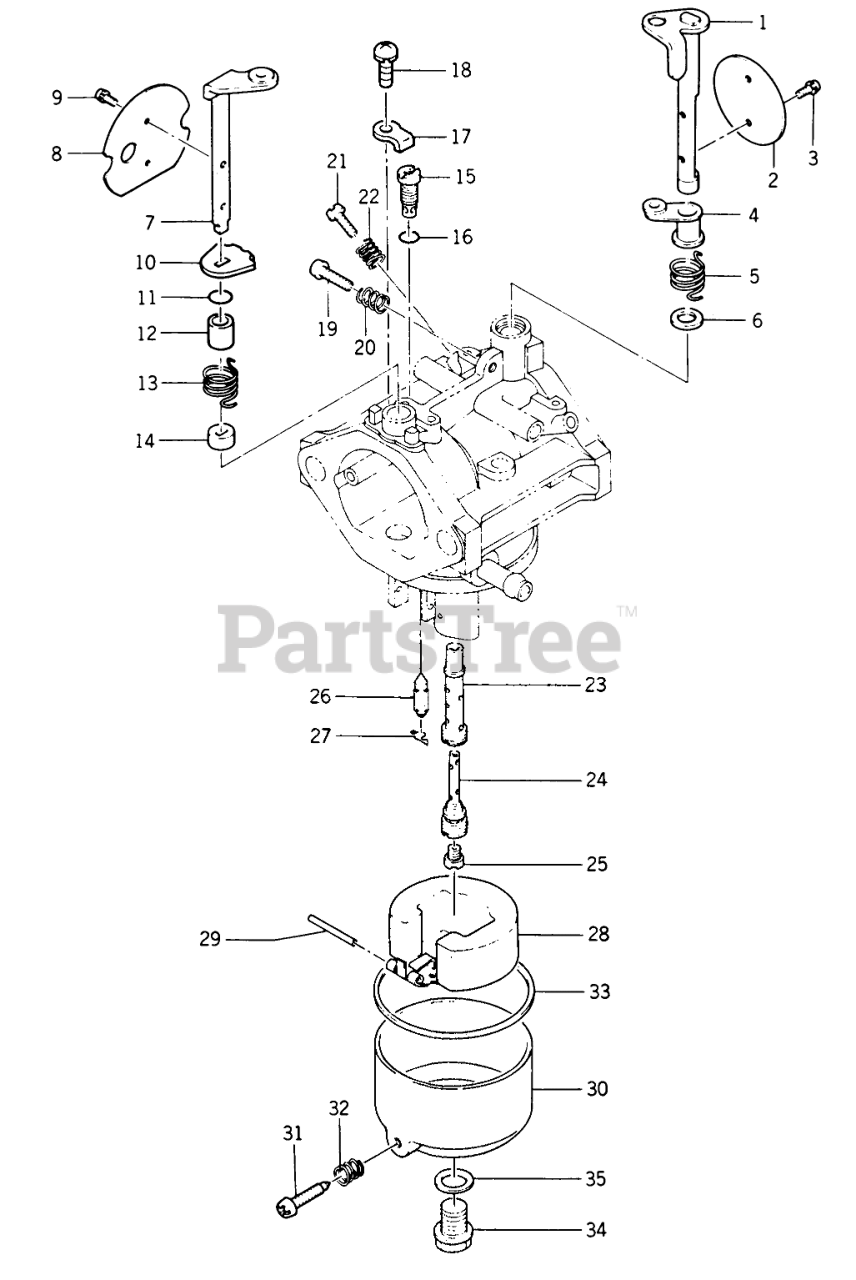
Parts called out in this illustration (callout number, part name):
1	SHAFT THROTTLE
2	VALVE THROTTLE
3	SCREW-THROTTLE PLATE
4	RING BUSHING
5	SPRING
6	Seal
7	SHAFT CHOKE
8	VALVE CHOKE
9	SCREW
10	COLLAR
13	SPRING
14	COLLAR
15	HOLDER-MAIN JET
16	O-RING
17	PLATE
18	SCREW
19	Screw 4 x 14
20	SPRING
21	SCREW PILOT AIR
22	SPRING
23	NOZZLE-MAIN
24	HOLDER-MAIN JET
25	JET-MAIN
26	NEEDLE VALVE ASSY
28	FLOAT
29	PIN-FLOAT
30	ASS'Y-FLOAT CHAMBER
31	SCREW-DRAIN
32	SPRING
33	GASKET
35	GASKET
